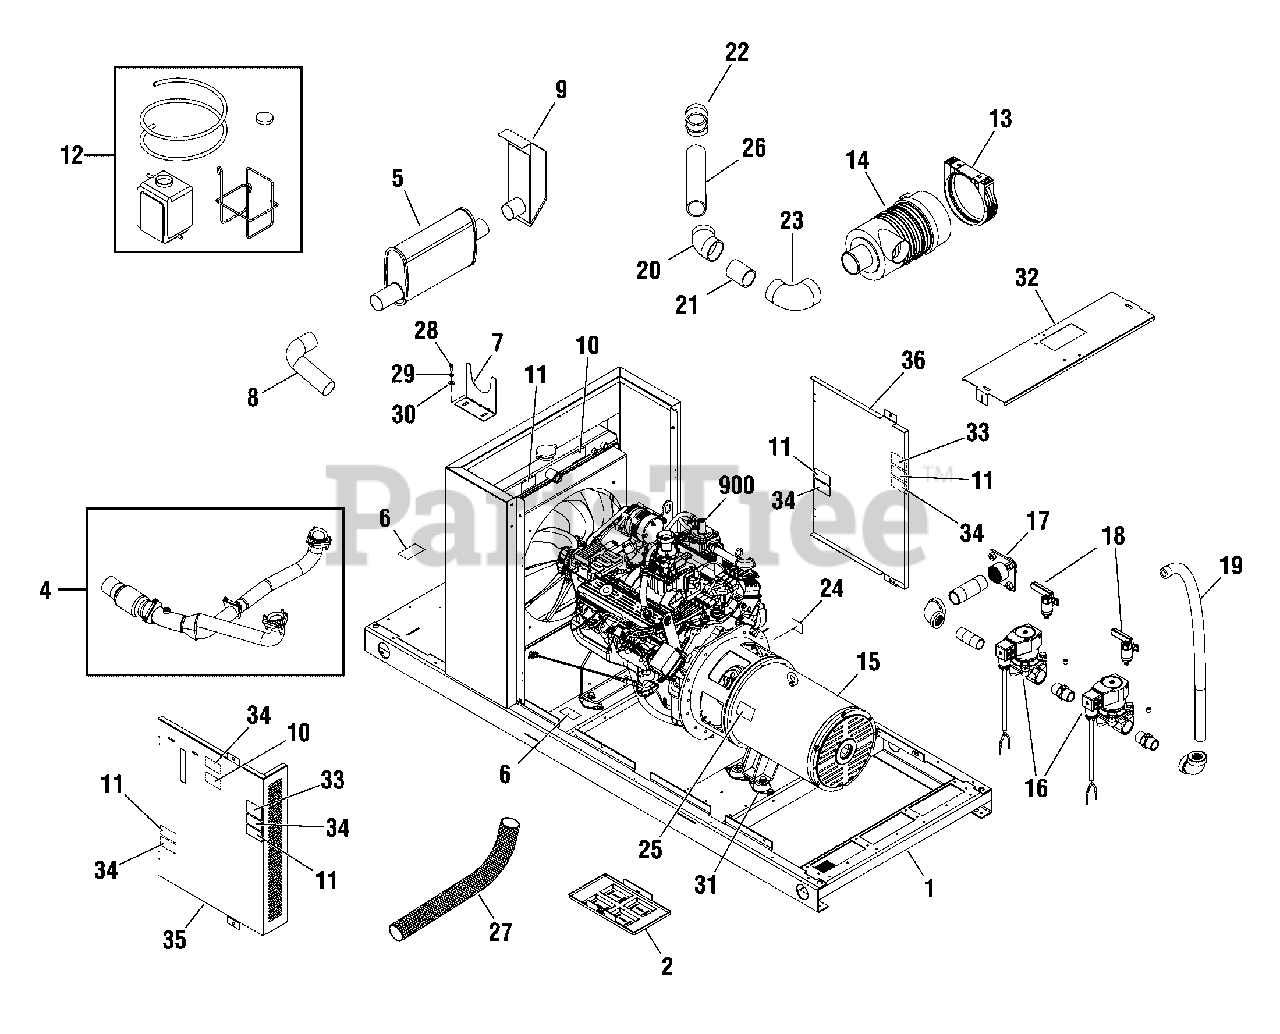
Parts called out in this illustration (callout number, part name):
1	BASE
4	KIT-EXHAUST
5	MUFFLER
6	DECAL
7	BRACKET-MUFFLER
9	DIFFUSER
11	DECAL
12	BOTTLE-OVERFLOW
24	DECAL
28	* CAPSCREW, Hex Head, 1/4-20 x 3/4
29	* WASHER, Lock, 1/4-M6
30	* WASHER, Flat, 1/4
31	MOUNT-VIBRATION
33	DECAL
34	DECAL
900	** ENGINE
